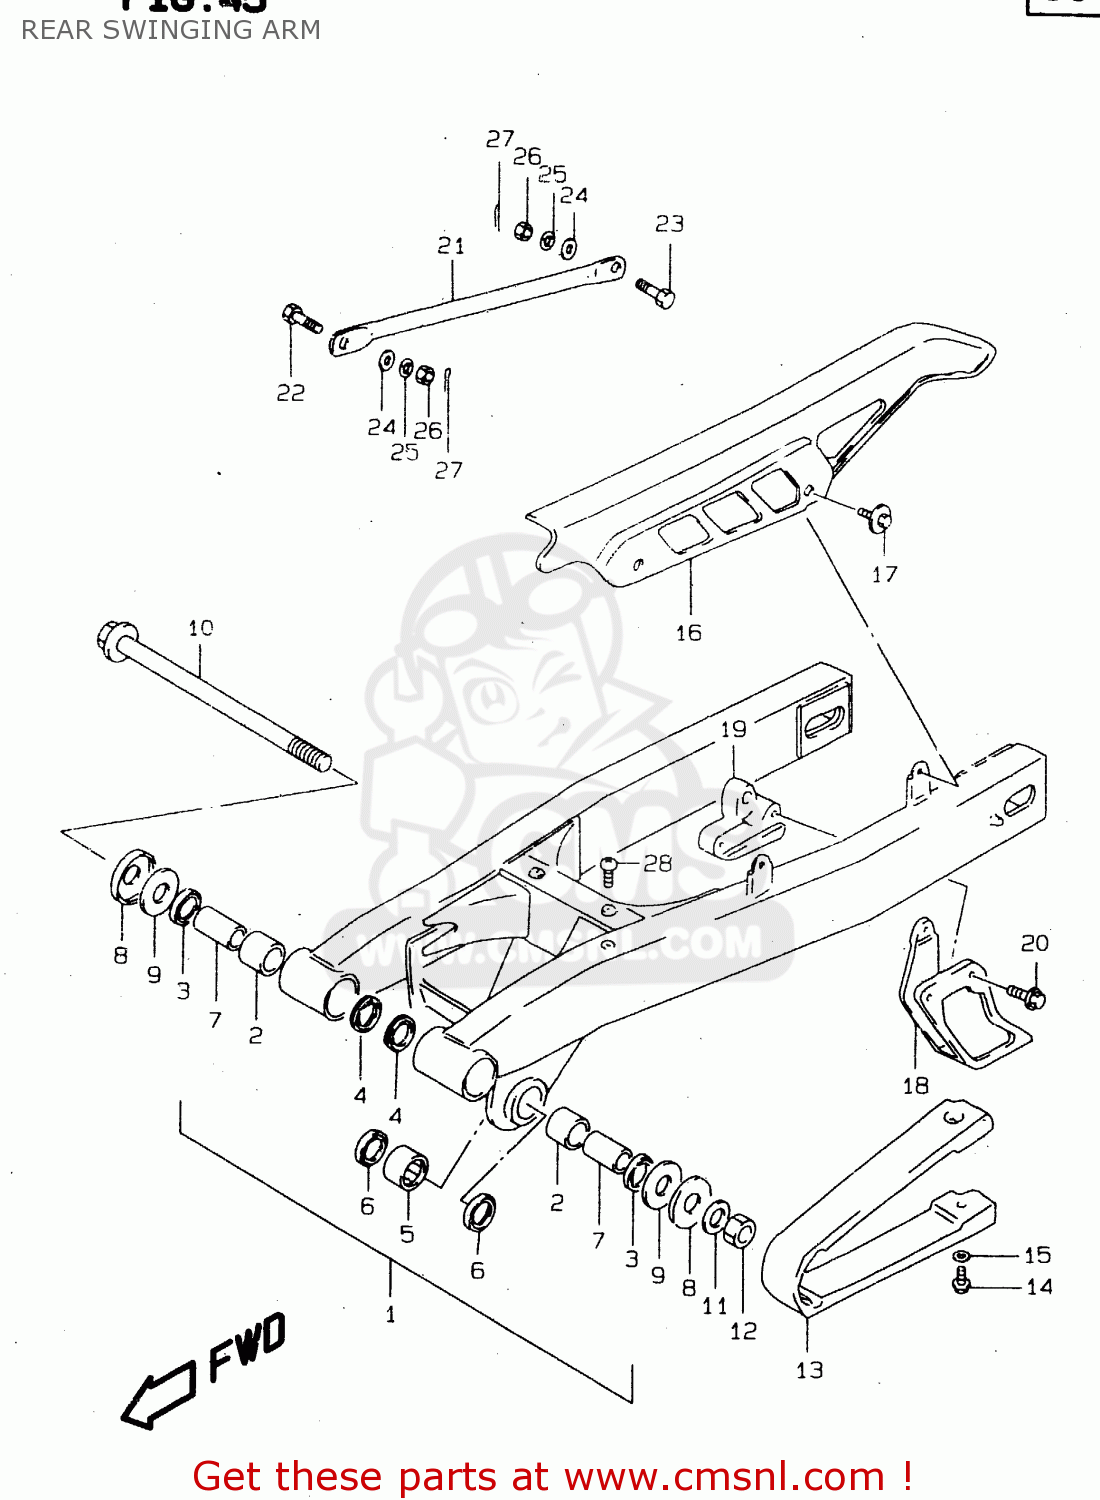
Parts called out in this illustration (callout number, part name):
1	SWINGINGARM ASSY,RR
2	BUSHING,RR SWGARM PIVOT
3	SEAL,OIL(20X27X5)
4	SEAL,OIL(20X27X5)
5	BEARING(20X27X25)
6	SEAL,CUSHION LEVER OUT DUST
7	SPACER,RR SWGARM PVT
8	COVER,RR SWGARM DUST SEAL
9	WASHER
10	SHAFT,RR SWINGINGARM PIVOT
11	WASHER
12	NUT
13	BUFFER,CHAIN TOUCH DEFENSE
14	BOLT
15	WASHER
16	CASE,CHAIN
17	BOLT(6X10)
18	GUIDE,CHAIN
19	RUBBER,CHAIN GUIDE
20	BOLT
21	TORQUE LINK,RR
22	BOLT(8X22)
23	BOLT(8X26.5)
24	WASHER
25	WASHER,LOCK
26	NUT
27	PIN 20X20
28	SCREW
